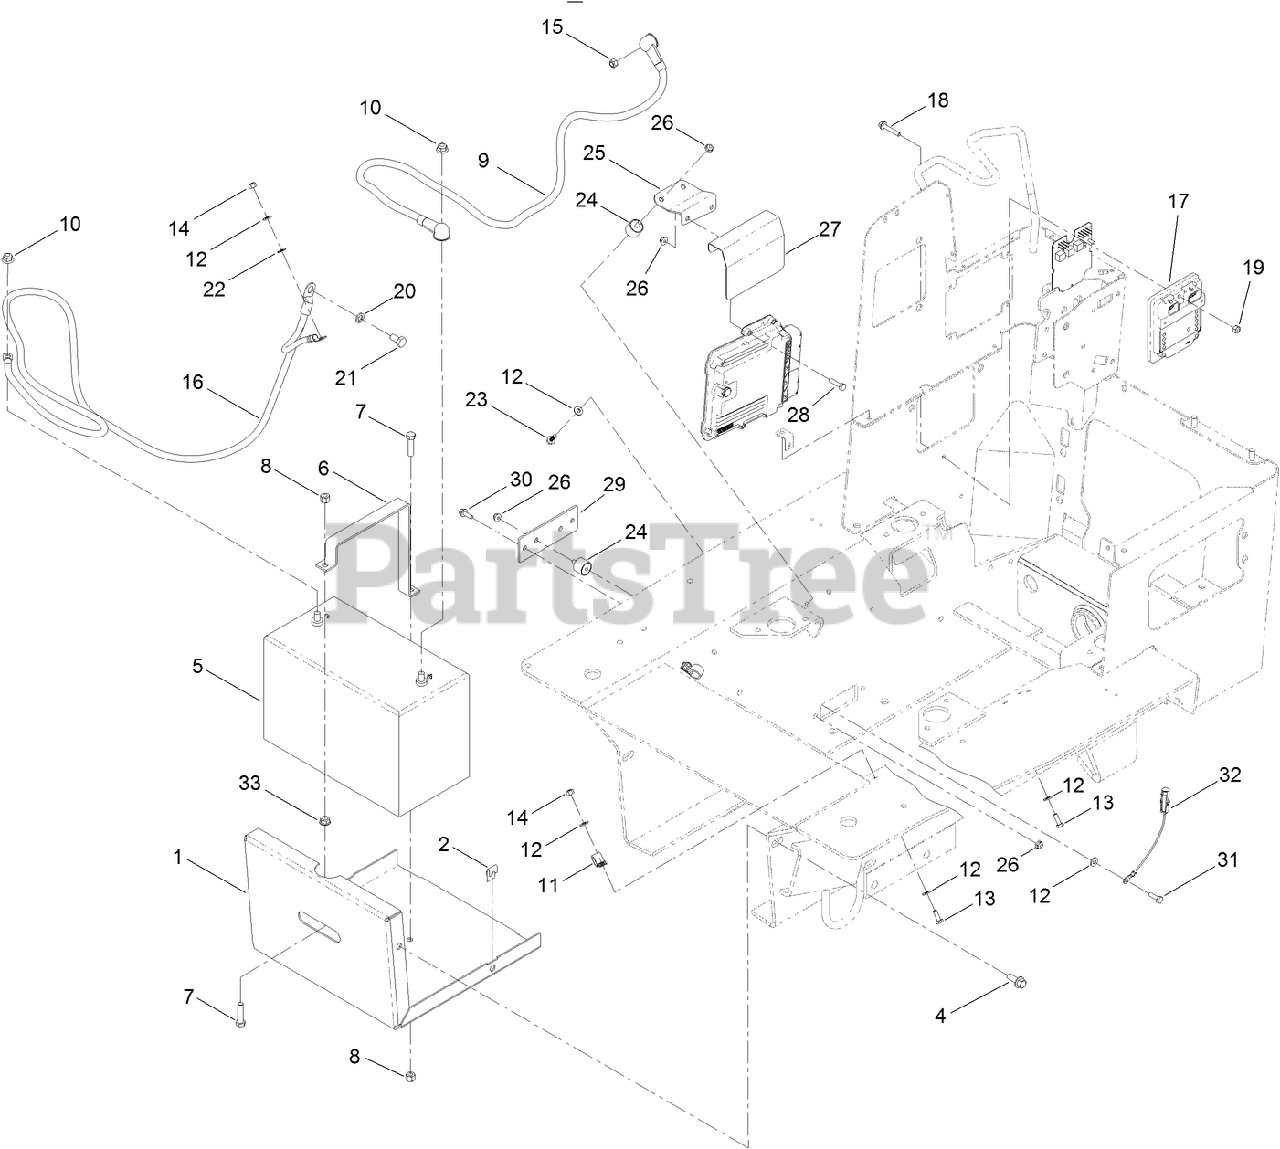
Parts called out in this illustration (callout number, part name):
1	RACK-BATTERY
2	NUT-SPRING
4	SCREW-HHF
5	BATTERY (1000CCA, WET)
6	BRACKET-BATTERY
7	SCREW-HH
8	NUT-HEX
9	CABLE-BATTERY, POSITIVE
10	NUT-HF, NI
11	CLAMP-CABLE
12	WASHER-FLAT
13	SCREW-HH
14	NUT-LOCK, CONE
15	NUT-LOCK, NI
16	CABLE-BATTERY, NEGATIVE
17	MODULE-CONTROL, PROSNEAK
18	SCREW-HHF
19	NUT-LOCK, NI
20	WASHER-LOCK
21	SCREW-HH
22	WASHER-LOCK
23	SCREW-HHF
24	MOUNT-CYLINDRICAL
25	PLATE-E C U
26	NUT-HF
27	COVER-DRIP
28	SCREW-HH
29	PLATE-E C U
30	SCREW-HHF
31	SCREW-HH
32	HARNESS-WIRE
33	NUT-HHF, WHIZ
